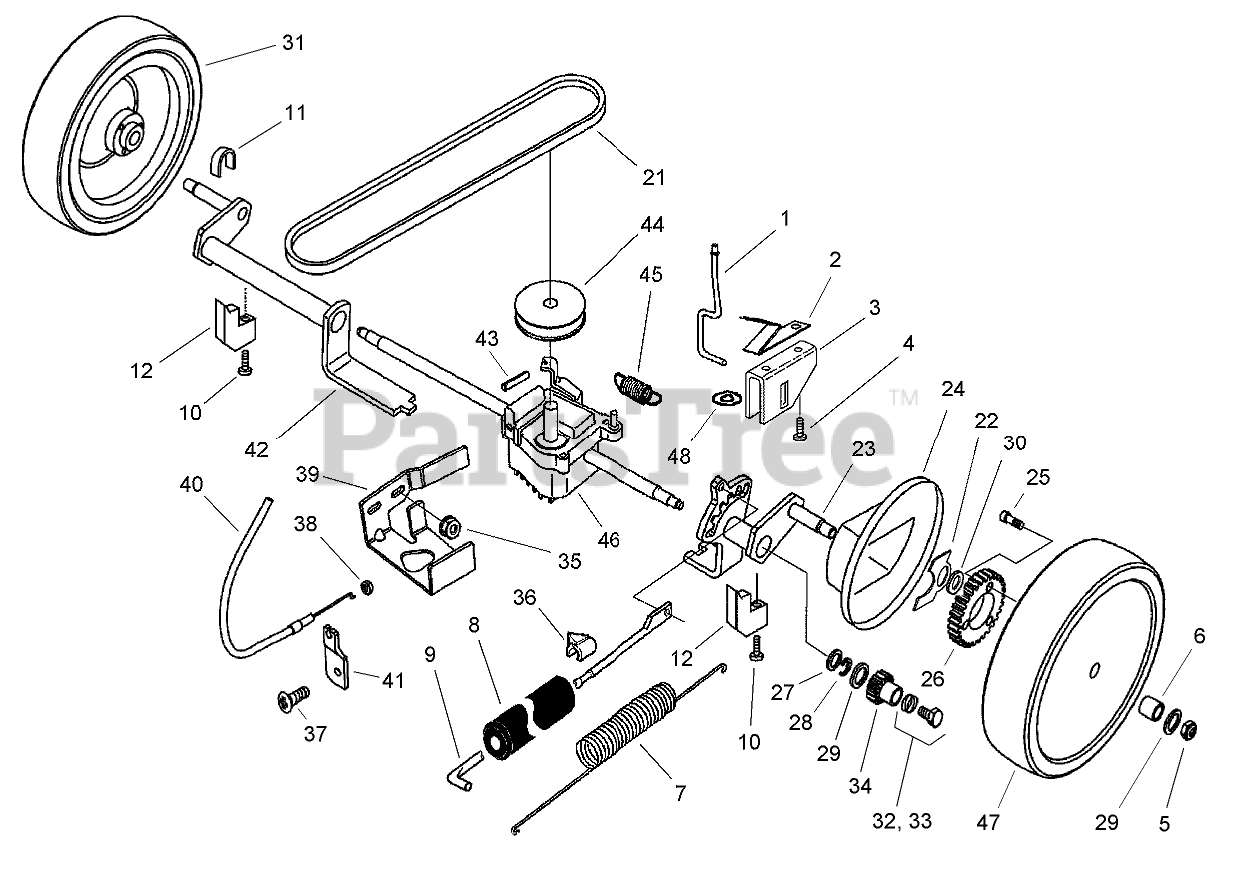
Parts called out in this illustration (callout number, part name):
1	ROD-TRIGGER
2	SPRING-RETURN, TRIGGER
3	SADDLE-HEIGHT OF CUT
4	SCREW-RH
5	NUT-HH
6	BUSHING
7	SPRING-COUNTERBALANCE
8	COVER-SPRING
9	ROD-LINK
10	SCREW-RETAINER
11	CAP-AXLE, REAR
12	RETAINER-AXLE
21	BELT - V
22	WHEEL-REAR
22	PLATE-LOCKING
23	AXLE-REAR, LEFT
24	COVER-WHEEL
25	SCREW-WHEEL
26	GEAR-WHEEL
27	WASHER-COVER
28	WASHER-AXLE
29	WASHER-GEAR
30	WASHER
31	WHEEL-REAR
32	LEFT BUSHING ASM
33	RIGHT BUSHING ASM
36	INDICATOR-HEIGHT OF CUT
37	SCREW-BRACKET
38	Nut-Cable
39	Guide-Belt
40	Cable-Drive
41	Retainer-Cable
42	AXLE-REAR, RIGHT
43	Pin-Roll
44	PULLEY-GEARBOX
45	Spring-Clutch
46	GEARBOX ASM
47	WHEEL-SMART, REAR
48	Washer
